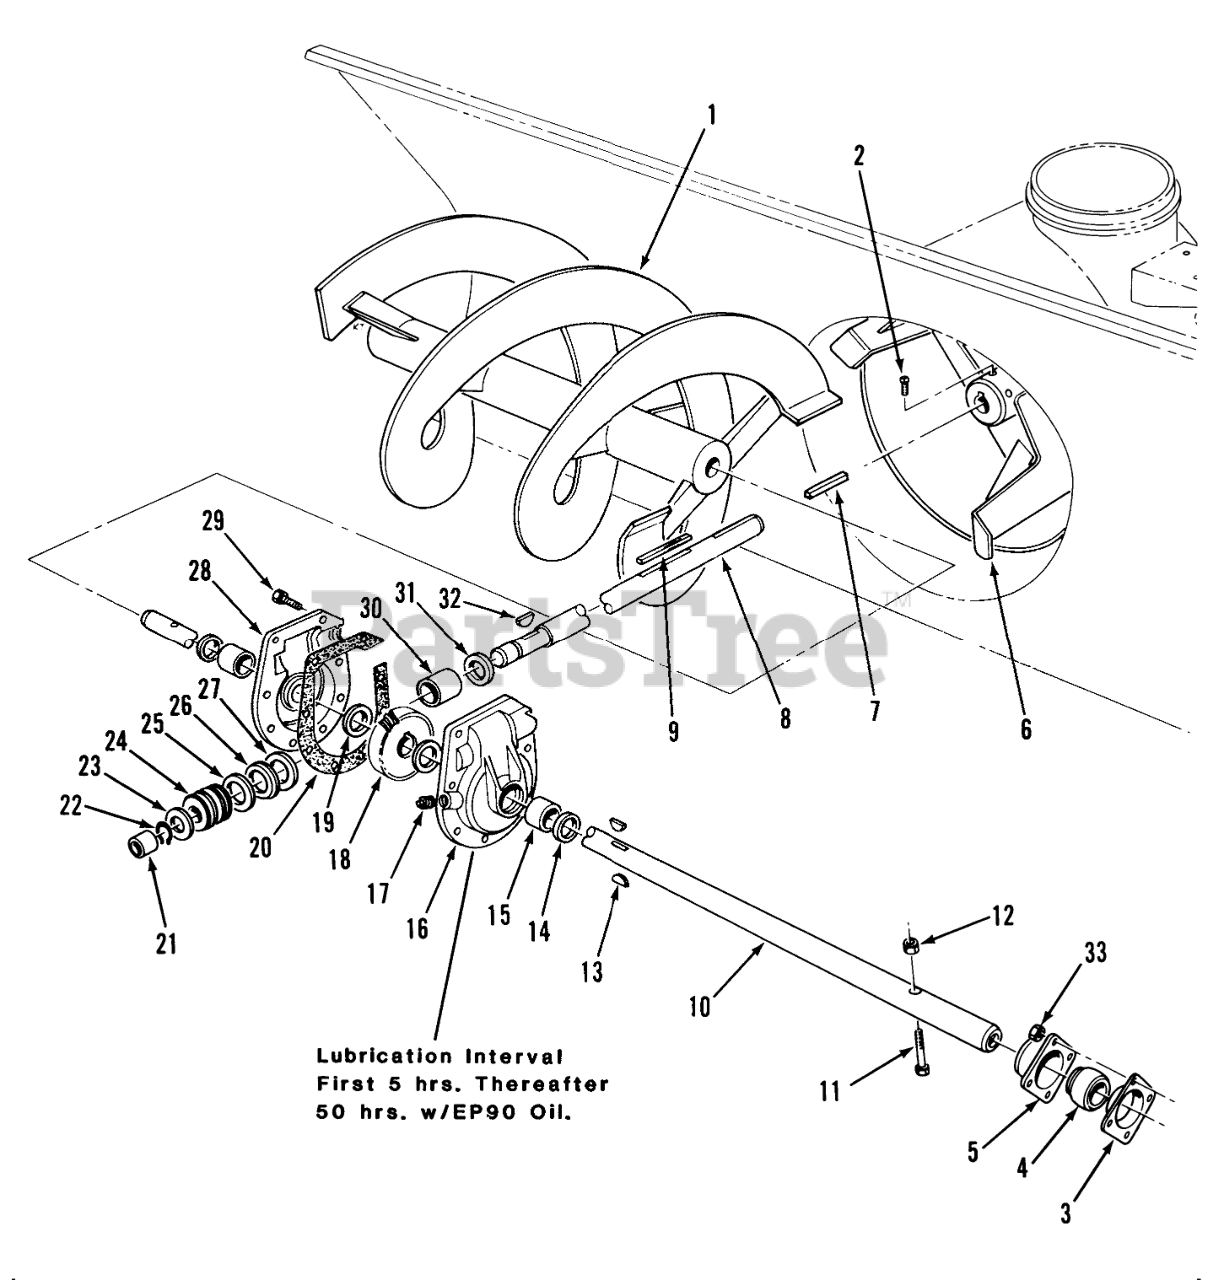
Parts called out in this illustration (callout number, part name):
1	Auger RH
1	Auger LH
2	Set Screw
3	BEARING-FLANGE, REAR
4	BEARING
5	BEARING-FLANGE, FRONT
6	IMPELLER ASM
7	KEY
8	SHAFT-IMPELLER
9	Washer
10	SHAFT-AUGER
11	Pin-Cotter
12	Nut
13	KEY-WOODRUFF
14	SEAL-OIL
15	BUSHING
16	Gear Case & Bushing Assy. (Includes Seals & Bushings)
17	PLUG-PIPE, SQH
18	GEAR-WORM, 27T
19	WASHER-THRUST
20	GASKET-CASE, GEAR
21	BUSHING
22	Ring-Snap
23	WASHER-THRUST
25	THRUST-WASHER
26	BEARING-THRUST
27	WASHER-THRUST
28	Gear Case & Bushing Assy. (Includes Seals & Bushings)
29	SCREW-TAPTITE
30	BUSHING-SPECIAL
31	RING-QUAD
32	KEY-WOODRUFF
33	Nut
